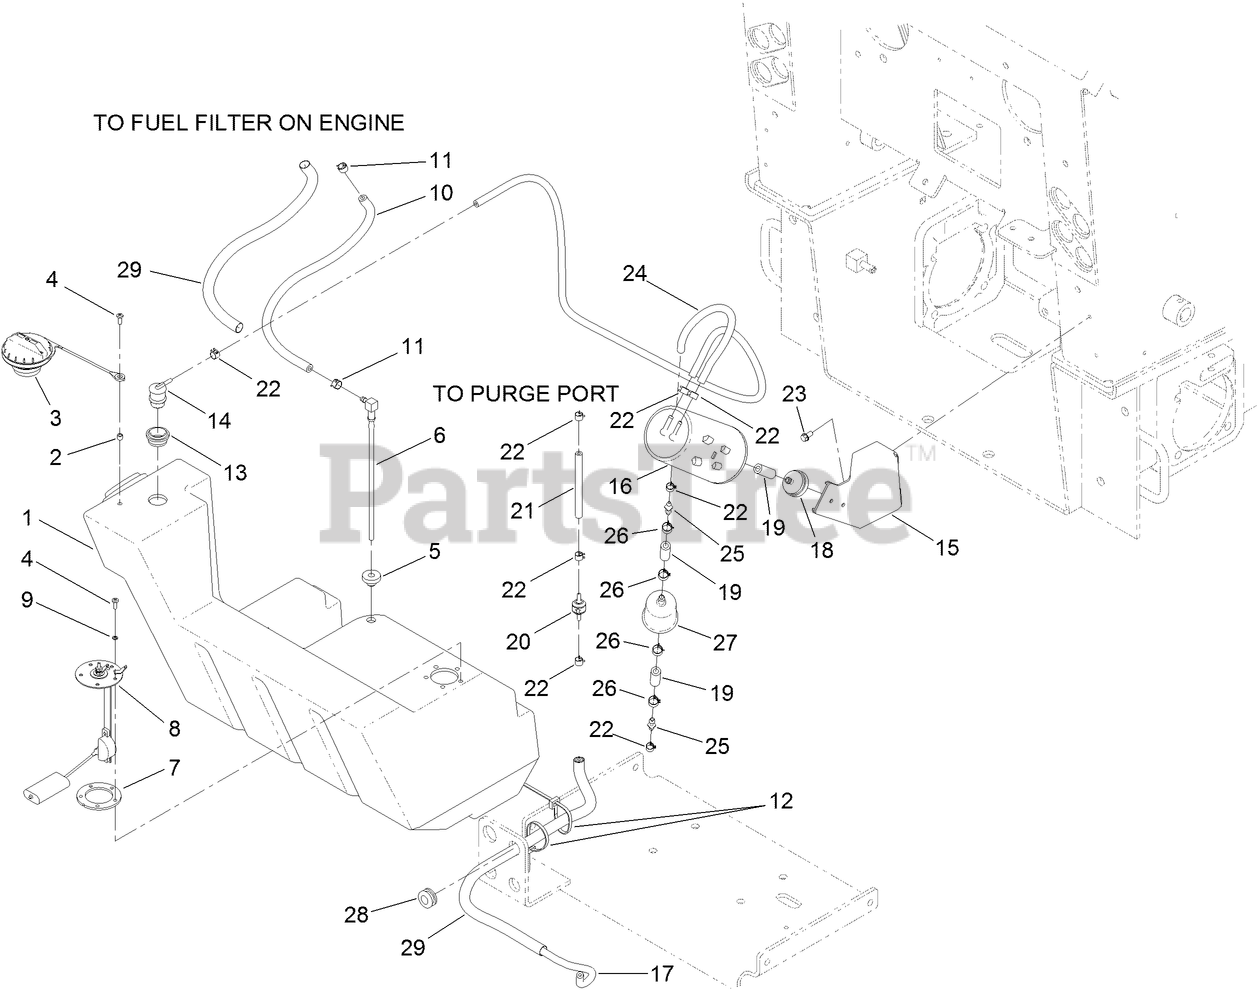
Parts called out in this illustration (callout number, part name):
1	TANK-FUEL
2	SPACER
3	CAP-FUEL
4	SCREW-PPH
5	BUSHING
6	PIPE-STAND
7	GASKET-SENDER, FUEL
8	SENDER-FUEL
9	WASHER-LOCK
10	HOSE-FUEL
11	CLAMP-HOSE
12	TIE-CABLE
13	GROMMET
14	VALVE-ROLLOVER
15	HOLDER-CANISTER
16	CANISTER-CARBON
17	HOSE-FUEL
18	FILTER-FUEL, INLINE
19	HOSE-FUEL
20	VALVE-CHECK, VACUUM
21	HOSE-FUEL
22	CLAMP-HOSE
23	SCREW-HWH
24	HOSE-FUEL
25	FITTING-STRAIGHT
26	CLAMP-HOSE
27	FILTER-FUEL
28	GROMMET
29	SLEEVE-THERMAL
